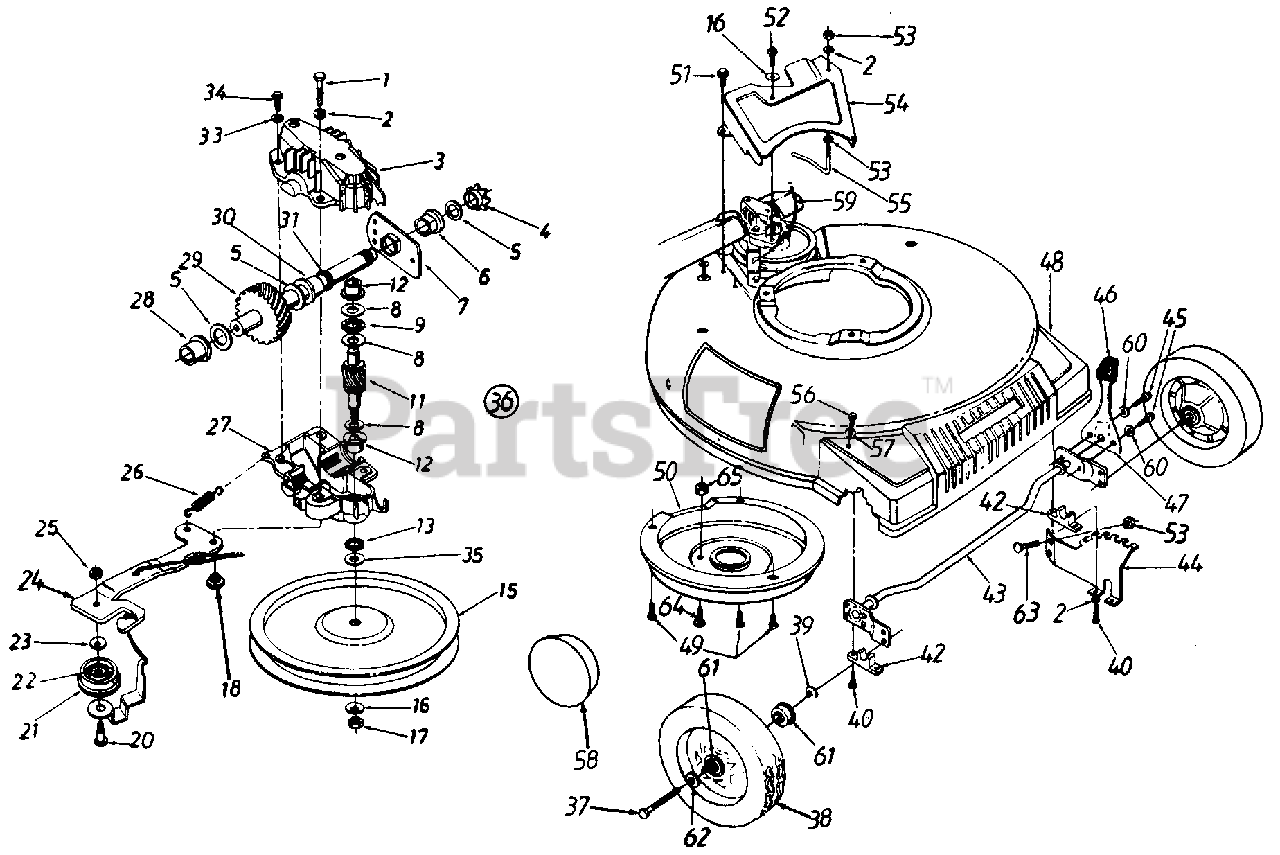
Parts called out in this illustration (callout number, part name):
1	Hex Patch Bolt 1/4-20 x 1.25"
2	L-Wash. 1/4" I.D.
3	Upper Hsg. Half
4	#48 Sprocket 7 T x 1/2 Pitch
5	Fl-Wash. 5/8" I.D. x .30
6	Hex Flange Brg. .631" I.D.
8	Thrust Wash. .382" I.D. x .70" O.D.
9	Thrust Bearing .375" I.D. x .812" O.D.
11	11 Tooth Pinion Shaft
12	Flange Bearing
13	Oil Seal
15	Fl-Pulley 5.06" O.D.
16	Bell-Wash. .265" I.D. x .75"
17	Hex L-Nut 1/4-28 L.H. Thd.
18	Shld. Spacer .375" Dia. x .170
20	Shld. Bolt .375" Dia x .40"
21	Fl-Idler Plastic 1.50" Dia.
22	Needle Brg. .375" x .31
24	Idler Brk't. Ass'y.
25	Hex Patch L-Nut 1/4-28 Thd.
26	Extension Spring 1.12" Lg.
27	Lower Hsg. Half
28	Flange Bearing .566 Dia.
29	Shaft Ass'y.
30	Flange Bearing .629 Dia.
31	Oil Seal .625 Dia.
33	L-Wash. #10 I.D.
34	Hex B-Tap Scr. #10 x .62"
35	Hex Washer .26" x .88"
36	Transmission Comp.
37	Front Axle Bolt
38	Wheel Ass'y. Comp.
39	Bell-Wash. .380" I.D. x .88
40	Hex Wash. Hd. Tap Scr. 1/4-20 x 1" Lg.
42	Block Bushing
45	Hex TT-Tap Scr. 1/4-20 x .38"
46	Knob
47	Spring Lever
48	Plastic Front End
49	Hex B-Tap Scr. 1/4" x .38"
52	Hex Wash. Hd. B-Tap Scr. (1/4 x .62" (Spec.)
53	Hex Flange L-Nut 1/4-20 Thd.
54	Transmission Belt Guard
55	S.P. Belt Guard
56	Torx Scr. 5/16 x .75" Lg.
57	Bell-Wash. .345" I.D. x .88"
58	Hub Cap
59	S.P. Cable 44" Lg.
60	External L-Wash. 1/4" I.D.
61	Ball Bearing 1/2" I.D.
62	Wave Wash. .53" I.D.
63	Carriage Bolt .5" Lg.
64	Mach. Scr. 1/4-20 x 2" Lg.
65	Hex L-Nut 1/4-20 Thd.
